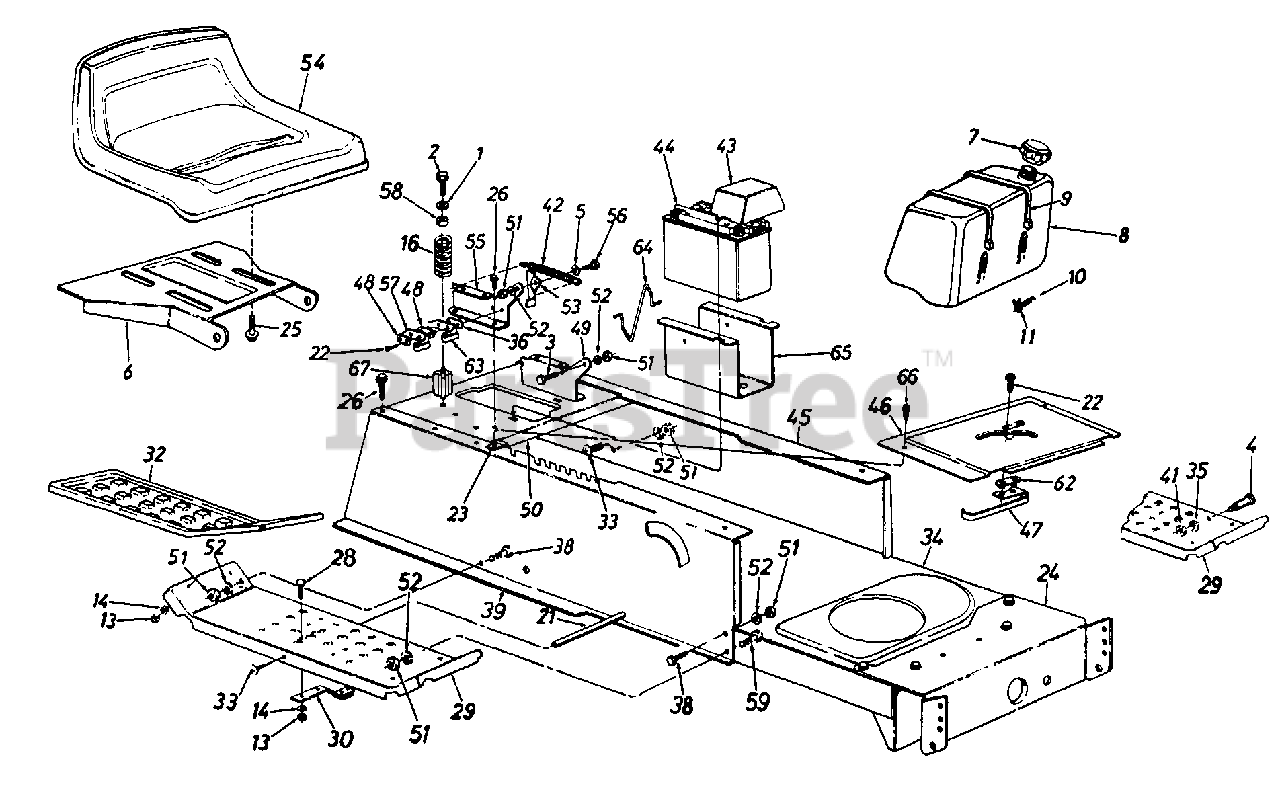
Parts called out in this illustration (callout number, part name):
1	Fl-Wash. .344" I.D. x .875"
2	Hex Wash. Hd. Tap Scr. 5/16-18 x 3.25" Lg.
3	Shld. Bolt .437" Dia. x .162"
4	Shld. Bolt .50" Dia. x .84"
5	Spr-Wash. .445" I.D. x .75
6	Seat Pivot Bracket
7	Fuel Cap
8	Fuel Tank
9	Tie Strap
10	Fuel Line
11	Hose Clamp
13	Hex Nut 1/4-20 Thd.
14	L-Wash. 1/4" I.D.
16	Compression Spring
21	Running Board Rod
22	Hex Wash. Hd. AB-Tap Scr. #8 x .50" Lg.
23	Speed Nut #10Z
24	Front Pivot Brkt.
25	Hex Tap Scr. 3/8-16 x .75"
26	Hex Wash. Hd. AB-Tap Scr. 5/16 x .75" Lg.
28	Carriage Bolt 1/4-20 x .62"
29	Running Board
30	Blade Brake Ass'y.
32	Rubber Foot Pad-L.H.
33	Truss Mach. Scr. 5/16-18 x .75" Lg.
34	Lower Frame
35	L-Wash. 3/8" I.D.
36	Insulator Boss Plate
38	Hex Bolt 5/16-18 x .75" Lg.
39	638/N Upper Frame-R.H.
41	Hex Nut 3/8-16 Thd.
42	Extension Spring 5.31" Lg.
43	Battery Cover
44	12-V Battery
45	Upper Frame-L.H.
46	Shift Cover
47	Reverse Safety Switch
48	Insulator Plate
52	L-Wash. 5/16" I.D.
53	Seat Lift Brkt.
54	Seat 8-7/8" High
56	Shld. Bolt .437" Dia. x .268"
57	Spring Switch
58	Bushing
59	Hex Wash. TT-Tap Scr. 5/16-18 x 7/8" Lg.
62	Insulator Nut Plate
63	Safety Switch
64	Battery Tray Clip
65	Battery Tray
66	Truss Mach. B-Tap Scr. #10 x .5" Lg.
67	Spring Spacer
